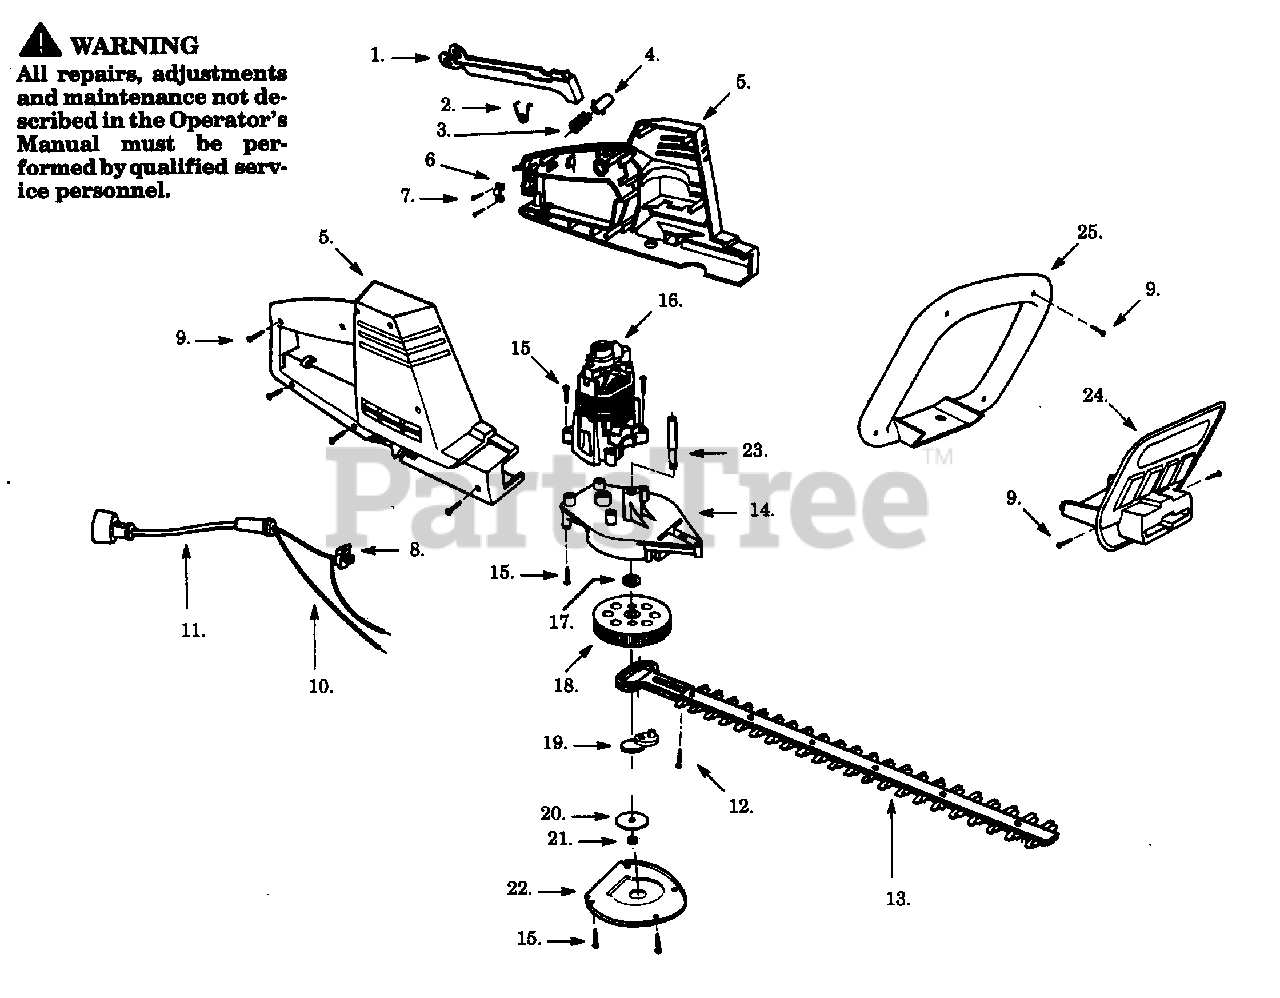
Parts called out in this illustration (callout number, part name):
1	Trigger Switch
2	Spring Clip
3	Spring-Trigger Lock
4	Button-Trigger Lock
5	Housing Set (R&L)
6	Cordset Clamp
8	Switch (On/Off)
10	Harness Ass'y. (Incl. 8 & 11)
13	Blade Ass'y., 20"
13	Blade Ass'y., 24"
14	Gear Box Ass'y.
16	Motor Ass'y.
19	Drive Cam
22	Plate Cover
25	Handle Ass'y. (Incl. 9)
